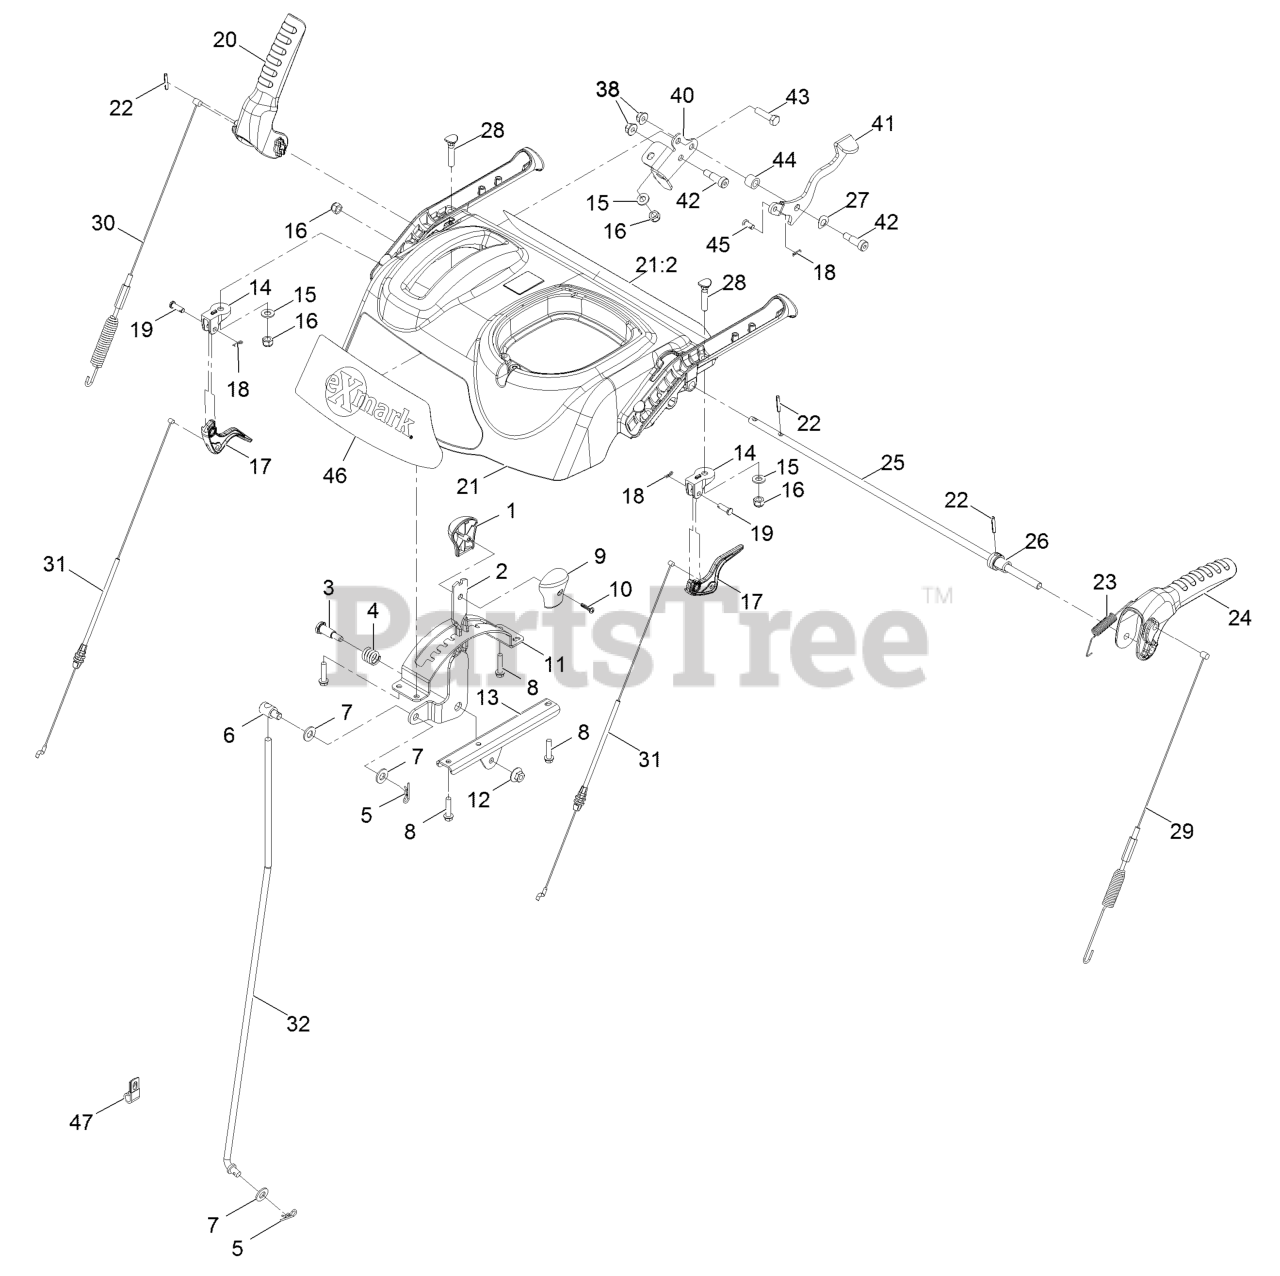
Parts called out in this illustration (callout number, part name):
1	Knob-Shift, RH
2	Selector-Speed
3	Screw-Shoulder
4	Spring-Compression
5	Pin-Cotter
6	Trunnion-Rod
7	Washer-3/8 Sae
8	Screw-Plastite
9	Knob-Shift, LH
10	Screw-PPH
11	Guide-Selector, Speed
12	Nut-HHF
13	Bracket-Selector, Speed
14	Mount-Clutch, Lever
15	Washer-Flat
16	Nut-Nyloc 5/16-18
17	Lever-Clutch
18	Pin-Hair
19	Pin-Clevis 1/4 X 3/4
20	Lever-Auger
21	Panel, Control W/Decal Ce Xb
21:2	Decal-Control Panel Back, Tss (Ce Xb)
22	Pin-Spring
23	Spring-Tension
24	Lever-Traction
25	Rod-Lockout
26	Cam-Lockout
27	Washer-Spring
28	Screw-Handle
29	Cable-Traction
30	Cable-Auger
31	Cable-Clutch
32	Rod-Shift
38	Nut-Nyloc 5/16-18 Flg
40	Bracket-Lever, Broom Angle
41	Lever-Thumb, Broom Angle
42	Screw-Shoulder, HSH
43	Screw-HH 5/16-18 X 1 1/4
44	Tube-Spacer
45	Pin-Clevis 1/4 X 1/2
46	Decal-Exmark Logo
47	Clip-Loom 3/8
